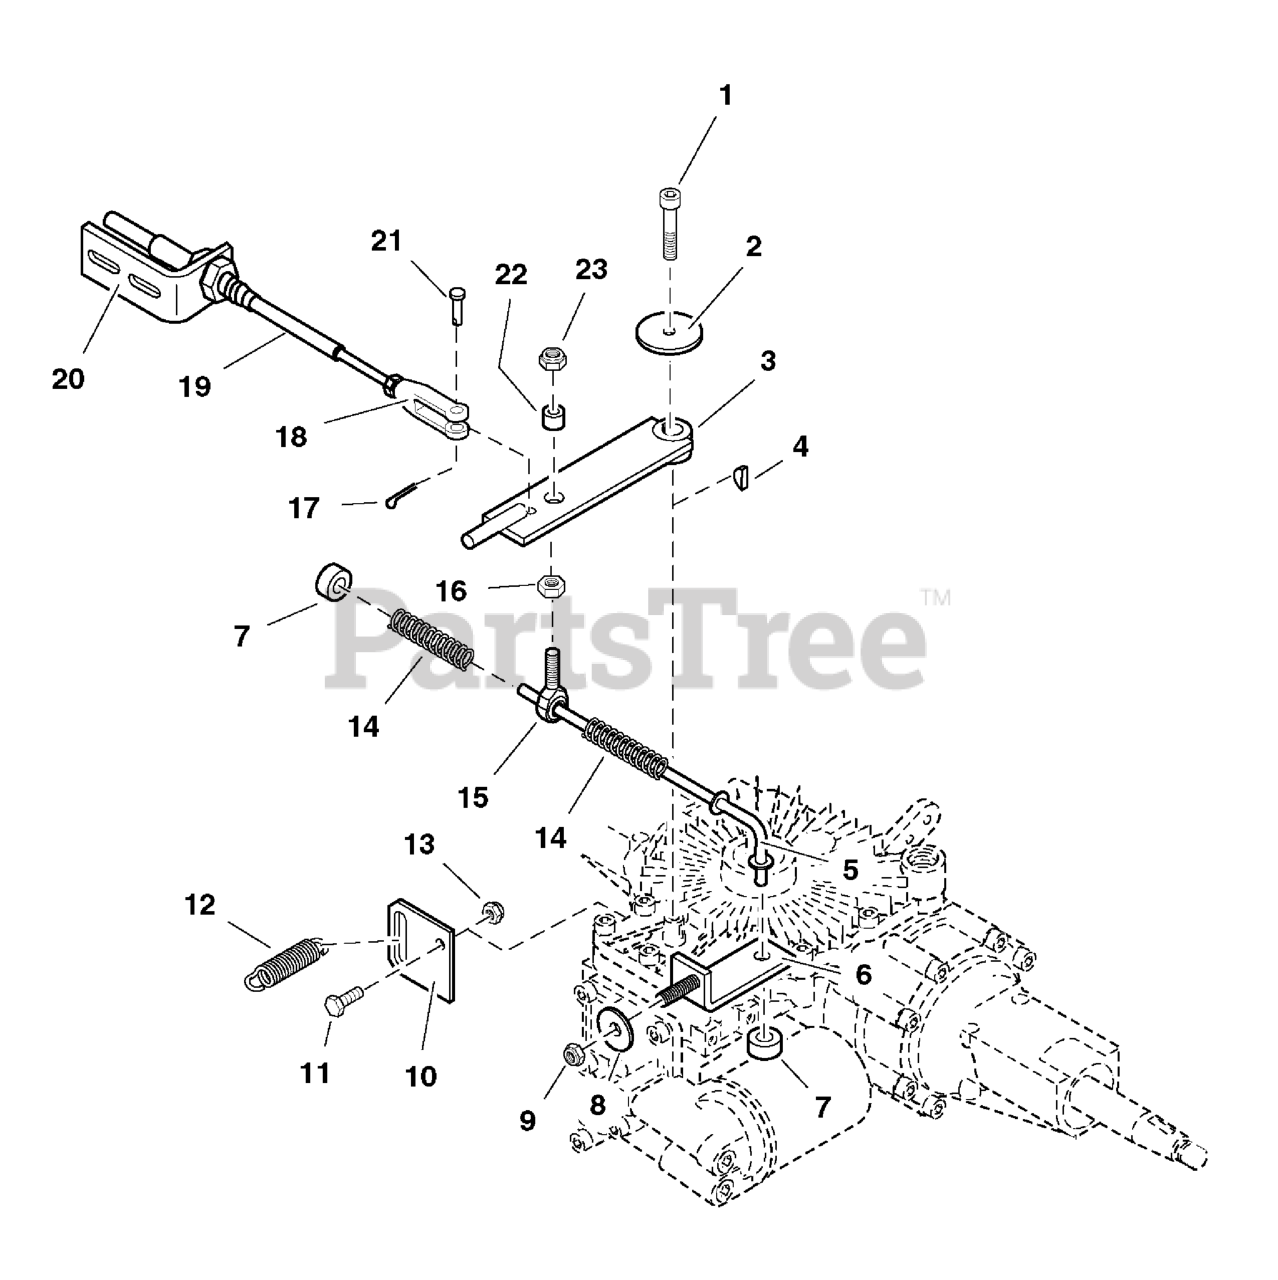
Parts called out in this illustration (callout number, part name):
1	BOLT, Allen Head, 1/4-20 x 1-1/2
2	WASHER, .265 x 1.50 x .109
3	TRANSMISSION CONTROL ARM
4	KEY, #3 Woodruff
5	ROD, NEUTRAL SPRING WELDMENT
6	Spring Anchor
7	COLLAR, 5/16" Set
8	WASHER, 5/16" Fender
9	NUT, 5/16-18 Hex Nylon Lock
10	DUMP VALVE LEVER
11	BOLT, 1/4-20 X 1" GD5 CZ
12	SPRING, Extension
13	NUT, 1/4-20 HEX NYLON LOCK
14	SPRING, Compression
15	BALL JOINT, 3/8-24 Male
16	NUT, 3/8-24 Hex
17	COTTER PIN, 1/16" x 1/2"
19	CABLE, Speed Control
20	CABLE BRACKET
21	CLEVIS PIN, 1/4 x 1
22	SPACER, .38 x .50 x .27
23	NUT, 3/8-24 Hex Nylon Lock
